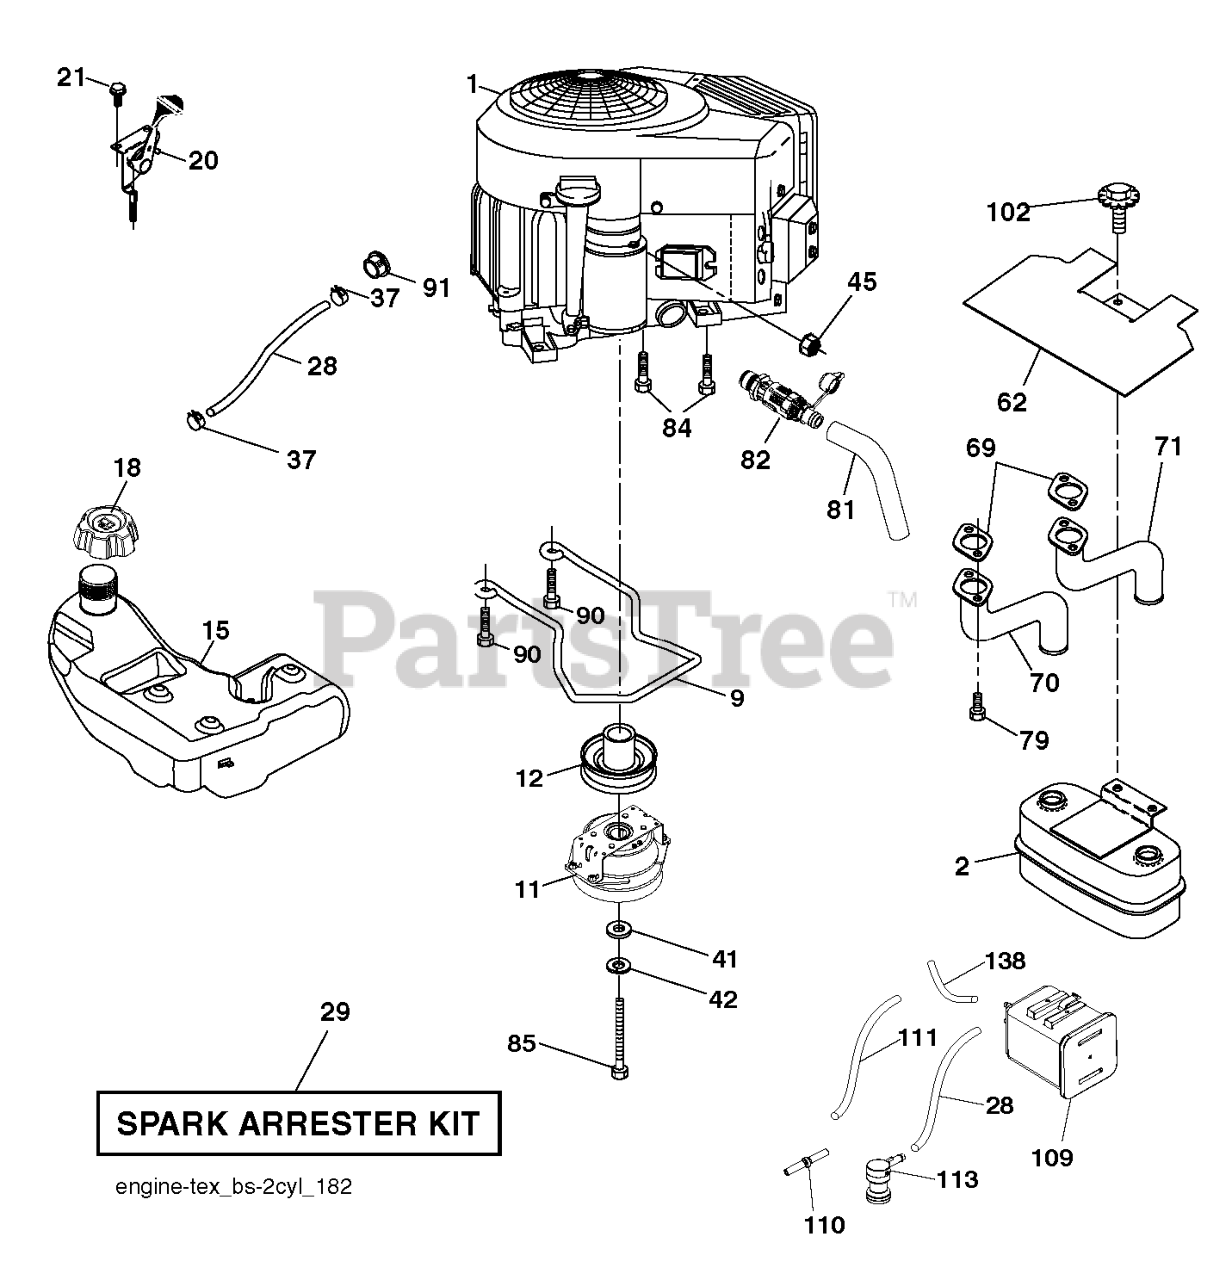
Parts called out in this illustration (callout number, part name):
2	MUFFLER.ASM.TWIN.MNTG.BRACKET
11	CLUTCH.OGURA.5.0PD.GT1.5A-EH07
12	PULLEY.ENGINE.TUFFTORQ
15	FUEL TANKS
18	FUEL CAP
18	Fuel Caps
20	THROTTLE CABLE
28	LINE.FUEL.64"REAR.EMIS
29	KIT.SPARK ARRESTOR 794945 B&S
37	HOSE CLAMP
62	SHIELD.HEAT.MUFFLER
69	GASKET.MUFFLER
70	EXHAUST.TUBE.LH.BS/TWIN
71	EXHAUST.TUBE.RH.B&S.TWIN.INTEK
81	TUBE, DRAIN OIL ASM.
82	VALUE.OIL.DRAIN
84	SCREW.3/8-16
85	BOLT.HEX.7/16-20X3.75.GR5.RED
90	SCREW 3/8-16X1
91	BUSHING.1.375OD
102	SCREW
109	CANNISTER, CARBON
110	VALVE.ASM.ANTI-SLOSH
111	TUBE.PURGE.FUEL.1875
113	VALVE.SLANT.CARTRDG.90 DEG.TEX
138	PURGE.LINE.36"REAR.CALIFORNIA
